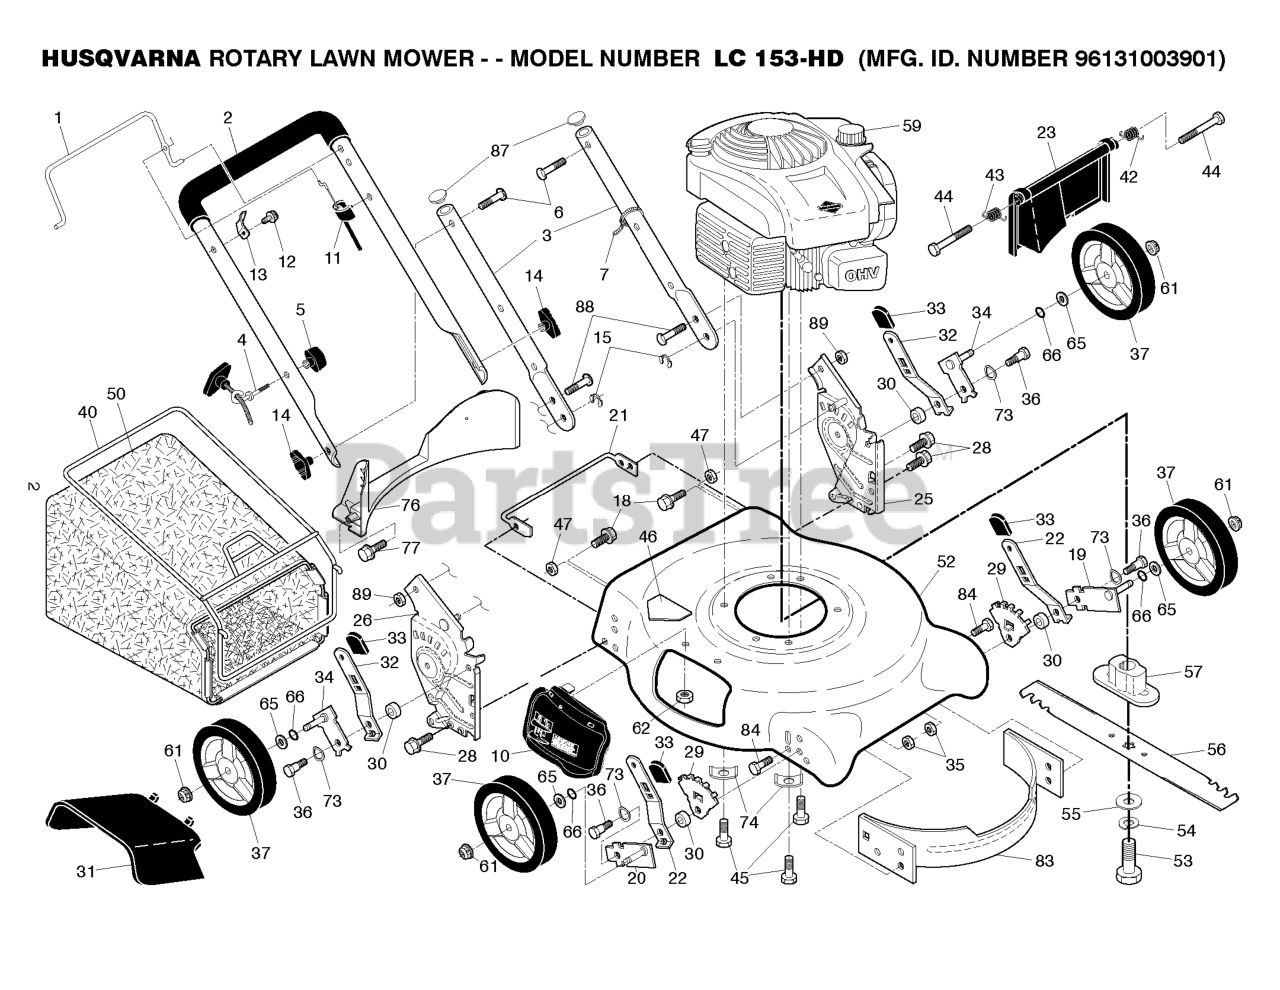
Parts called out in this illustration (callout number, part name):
1	CONTROL BAR
2	HANDLE.UP.ASM.DST.ECON.498.GRP
3	HANDLE.LOWER.DOME.BT.GREY
4	GUIDE.ROPE.BLK.ZINC.CHROM
5	T-KNOB.NEW ROPE GUIDE
6	BOLT, HANDLE 5/16-18X1.75
7	TIE GUIDE
11	CABLE.MZR.22.2012
13	BRACKET.UPSTOP.RT
14	KNOB, DEFLECTOR
15	KLIP RING TI
18	SCREW 1/4X20
19	AXLE ARM ASSY FRONT LH
20	AXLE ARM ASSY FRONT RH
21	FOOT.GUARD.21.DOM/FGD.CE.10
22	SELECTOR SPRING, FRONT
23	DOOR.REAR.21.DOMED.498
25	BRACKET.ASM.HAND.LW.21.LT.GREY
26	BRACKET.ASM.HAND.LW.21.RT.GREY
28	SCREW 14-20 X 5/8
29	WHEEL ADJ BRACKET FRONT
30	SPACER.HEIGHT.ADJUSTER
31	DEFLECTOR.CLIPPING.21.GREY
32	SPRING.SELECTOR.21RD.HTTRT.BZP
34	ARM.ASM.AXLE.REAR.5/9.POS.BZP
35	NUT.FLANGE.HEX.5/16X18.BLACK
36	SHOULDER BOLT 5/16-18
37	WHEEL & TIRES ASSY, FRONT
40	FRAME.BAG.21.REAR.DOMED.PUSH
42	SPRING.LH.22.REAR.DOOR.EZ.EMPT
43	SPRING.RH.22.REAR.DOOR.EZ.
45	BOLT 3/8-16X1-1/8
46	DECAL.INTERNATIONL.CUTFINGER
47	SCREW 14-20 X 5/8
50	GBAG.2323029ER.HU.VENT.GRY.SIL
52	HOUSING.21MC.DOME.ORANGE.CE
53	SCREW, HEX HD 3/8-24 X 1-3/8
54	LOCKWASHER
55	WASHER,HARDEN
56	BLADE.21.PUSH
57	ADAPTOR.BLADE.7/8
61	NUT.HEX.FLANGE.3/8-16.LO(3 2)
62	LOCKNUT.NYLOC.1/4-20
65	WASHER.FLAT.1/2
66	O-RING..070X.487.NEOPRENE
73	WASHER.CURVED.CYLINDRICAL
74	WASHER.ENGINE.BZP
76	BAFFLE.REAR.21DOM.REGRND.NATUR
77	SCREW.HX.13X.750
83	BAFFLE.FRONT.21.DOME.US
84	BOLT.5/16HEX.WHS.HD
87	PLUG.PLASTIC.7/8".14-20.GAUGE
88	BOLT.CARRIAGE.LN.5/16-18X.5/8
89	LOCKNUT-FLANGE 5/16-18
